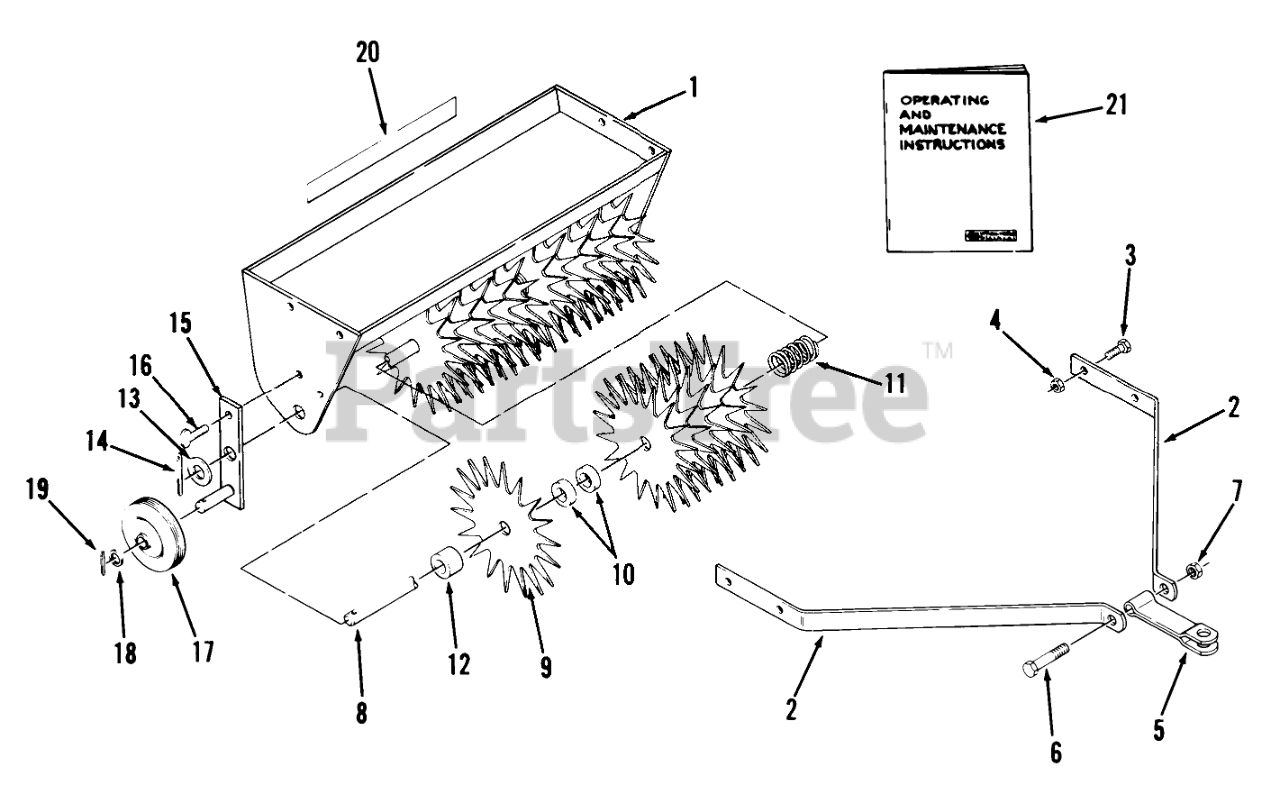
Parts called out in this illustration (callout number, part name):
1	Weight Tray Assembly
2	Side Bar
3	Bolt
4	Nut
5	Hitch Assembly
6	Bolt 1/2-13 x 3 1/2
7	Nut
9	Spike
10	Cup Spacer
11	Spring
12	BUSHING
13	Washer
14	Cotter Pin
15	R.H. Wheel Holder
15	L.H. Wheel Holder
16	Thumb Screw
17	Wheel
18	Washer
19	Cotter Pin
20	DECAL-WHEEL HORSE
21	Operating and Maintenance Instructions
